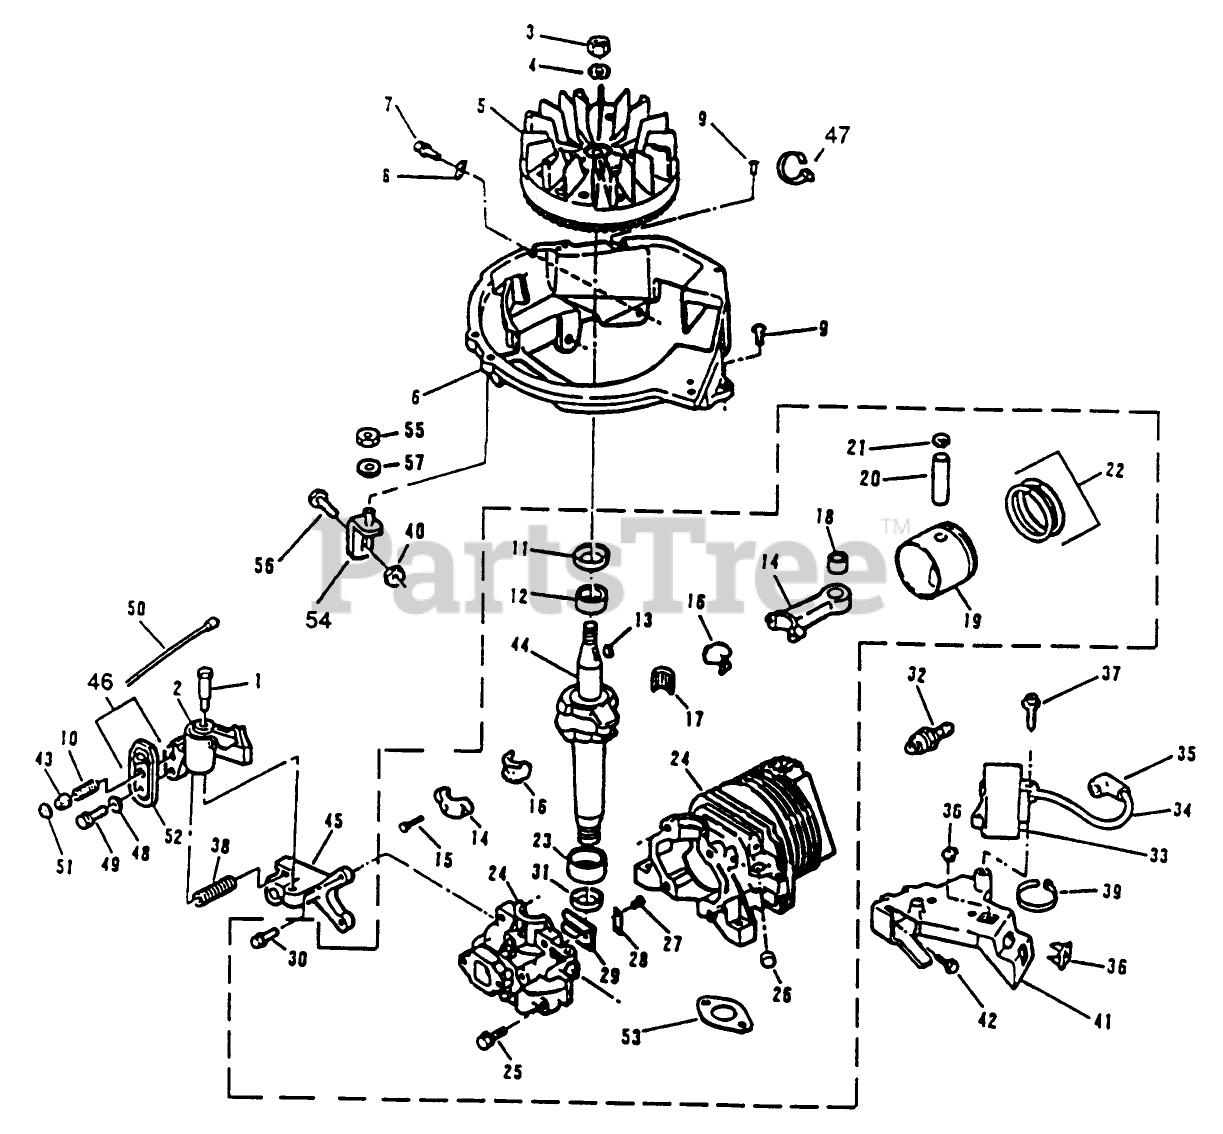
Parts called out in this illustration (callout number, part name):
1	SCREW-SHOULDER
3	NUT
5	FLYWHEEL ASSY F
6	BASE SHROUD F
7	SCREW-SEMS
9	SCREW F
10	SPRING
11	SEAL-OIL
12	BEARING V
13	KEY
15	SCREW-HSH
16	LINER ASM
17	BEARING-NEEDLE
18	BEARING AY F
21	RING-RETAINING
23	BEARING V
25	SCREW-H.W.HD. F
26	PLUG-CORE VF
27	SCREW-HH
28	PLATE-BACKUP, REED
30	SCREW
31	SEAL-OIL
32	SPARK PLUG
34	HT LEAD&COVER XEV
35	COVER & TERM. AY S
36	NUT-CLIP
38	SPRING-BRAKE
39	TIE-CABLE
40	NUT-LOCK F
41	C.D. BRKT F
42	SCREW F
43	ACTUATOR-LEVER, BRAKE
45	BRACKET-BRAKE F
50	WIRE LEAD AY F
51	RETAINER S
54	BRACE AY F
55	LOCKNUT E
56	BOLT F
57	WASHER S
